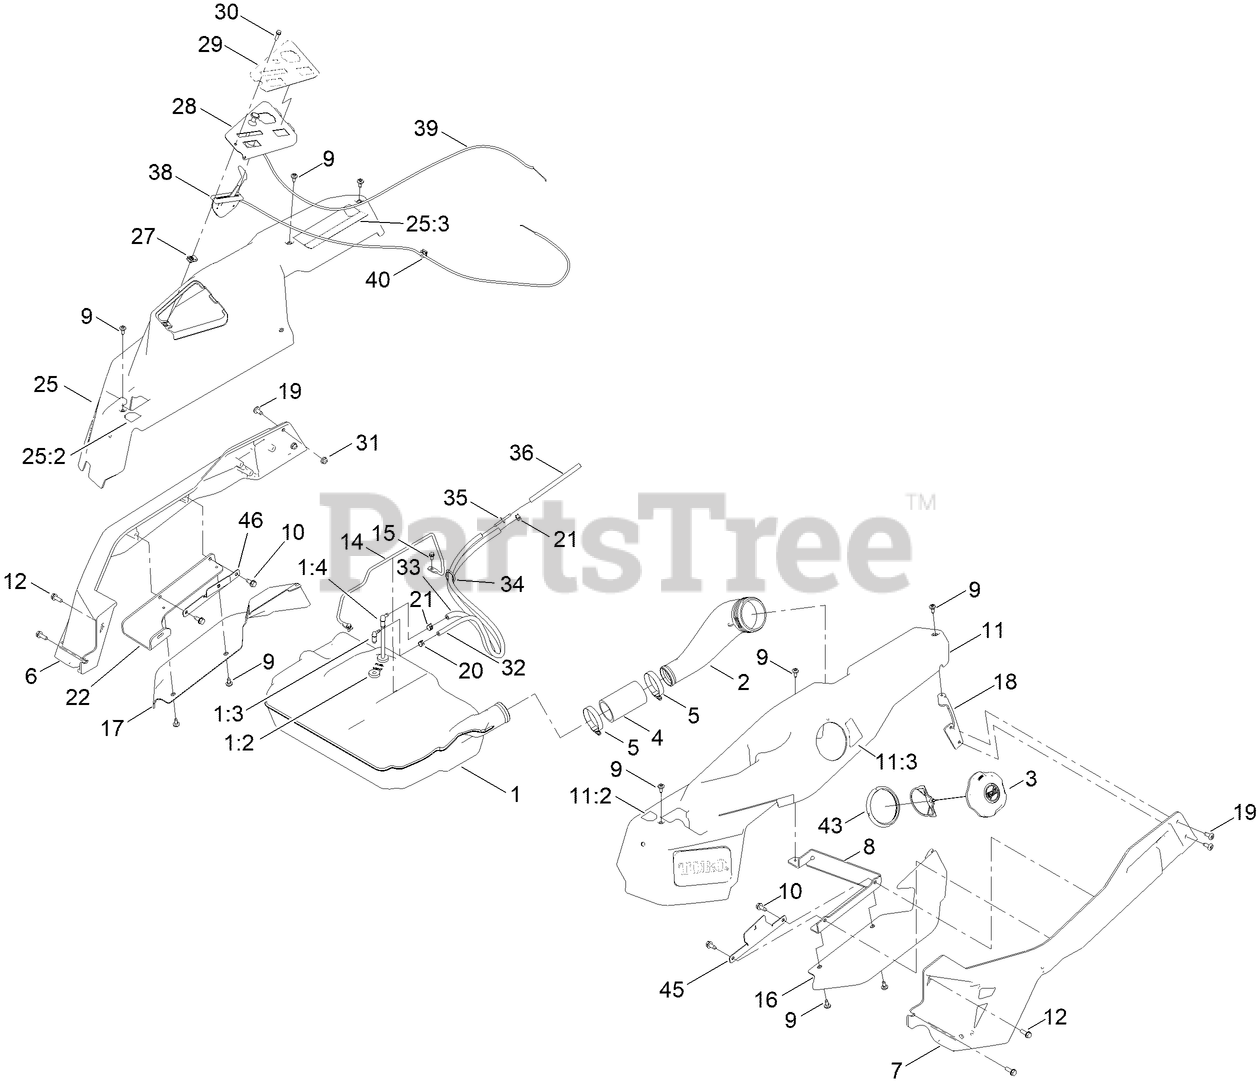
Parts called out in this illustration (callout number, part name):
1	TANK-FUEL ASM
1:2	BUSHING
1:3	FITTING-ELBOW 90
1:4	FITTING - PICKUP, FUEL
2	NECK-FILLER, FUEL
3	CAP-FUEL, RATCHETING
4	HOSE-FILLER, FUEL
5	CLAMP-HOSE
6	CAST-TUBE, RH [BLK-TXT]
7	CAST-TUBE, LH [BLK-TXT]
8	MOUNT-POD BRACKET LH
9	SCREW-SHOULDER
10	SCREW-HWHTF
11	POD ASM - LH W/DECALS
11:2	DECAL-CONTROL LEVER, LH
11:3	DECAL-FUEL FILL
12	SCREW-TAPTITE
14	ROD-HOLD DOWN
15	SCREW-HWH
16	FENDER-TIME CUTTER, LH
17	FENDER-TIME CUTTER, RH
18	BRACKET-REAR POD, LH
20	CLAMP-HOSE
21	CLAMP-HOSE
22	BRACKET-MR SPRING
25	POD ASM - RH , MR W/DECALS
25:2	DECAL-CONTROL LEVER, RH
25:3	DECAL - MYRIDE
28	PANEL-CONTROL
29	DECAL - CONTROL PANEL
30	SCREW-HWH
31	NUT-HF
32	HOSE-FUEL
33	HOSE-FUEL
34	CLIP-TIE
35	ADAPTER ORIFICE
36	HOSE-VENT
38	CABLE-THROTTLE
39	CABLE-CHOKE
40	CLIP-HARNESS
43	RING-RETAINING
45	BRACKET-ALIGNMENT, POD LH
46	BRACKET- ALIGNMENT, POD RH MR
